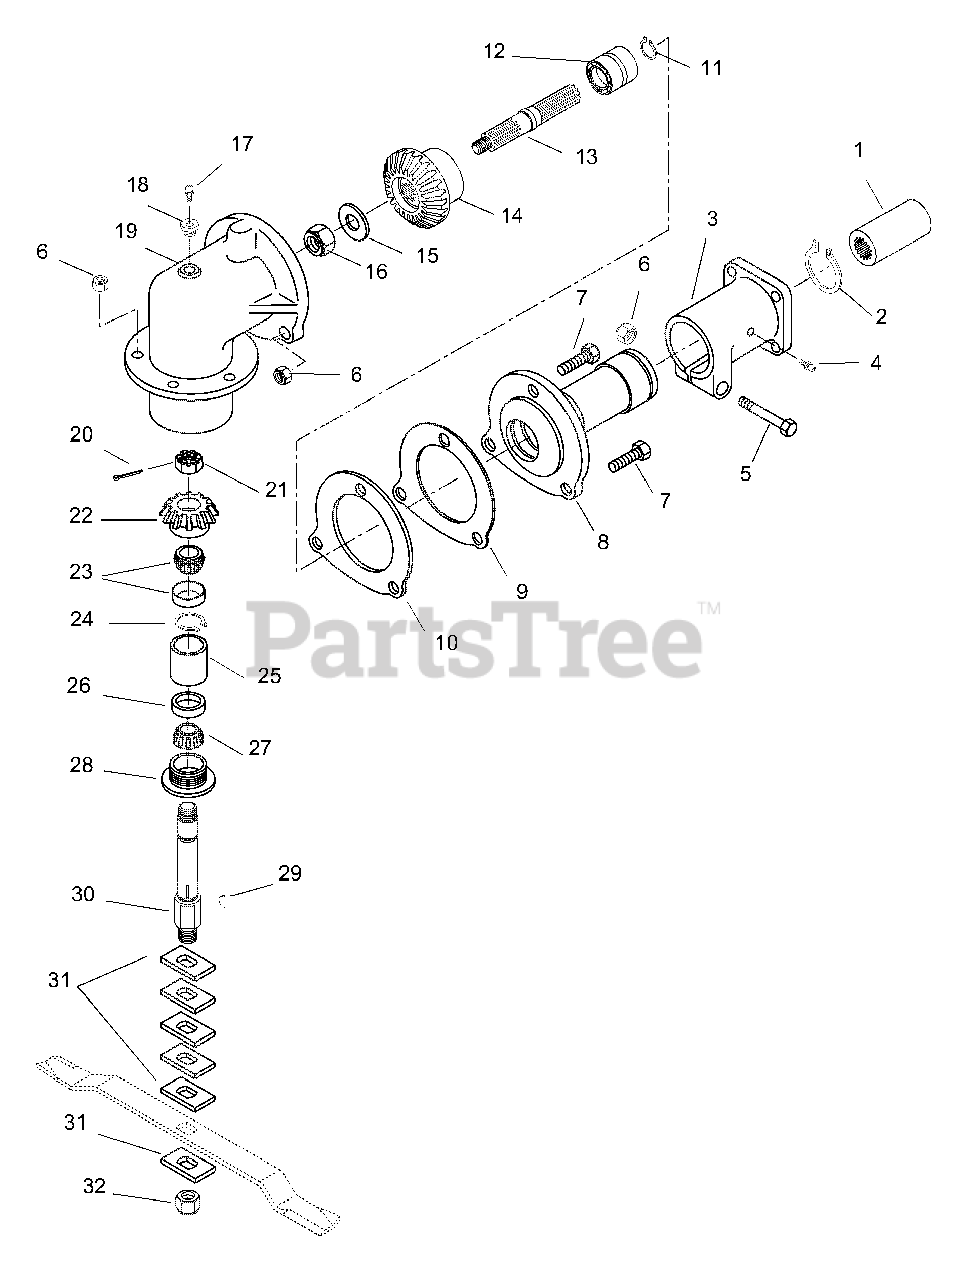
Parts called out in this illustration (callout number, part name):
1	Coupling
2	Ring-Retaining External 2.25 x .078
3	Casting-Swivel
4	Fitting-Lube .25-28 x .256
5	Bolt-Hex .50-13 x 3.25 Grade 5
6	Nut-Lock Nylon .50-13
7	Bolt-Hex .50-13 x 1.75 Grade 5
8	Housing-Shaft
9	Shim .005
10	Shim .020
11	Ring-Retaining: .937 Shaft
12	Assembly-Bearing: 1.000 x 1.980 x 1.243
13	Shaft-Drive
14	Gear-Bevel
15	Washer-Flat-Steel .656 x 1.31 x .095
16	Nut-Lock .625-18 Hex Head Type N
17	Fitting-Lube .125
18	Bushing-Reducing Pipe .5
19	Housing-Gear
20	Pin-Cotter .094 x 1.25
21	Nut-Hex .625-18 Slotted
22	Pinion Bevel
23	Assembly-Bearing Cup & Cone
24	Ring-Retaining-Internal 2.210 x .062
25	Bushing- 1.75 x 1.94 x 1.94, Steel
26	Cup-Bearing 1.980 x .42
27	Cone-Bearing 29 mm x .58
28	Seal
29	Key-Woodruff .13 x .38
30	Shaft-Rotor
31	Spacer-Cutting Height .25
32	Nut-Lock .875-9 Heat Treated Thin
